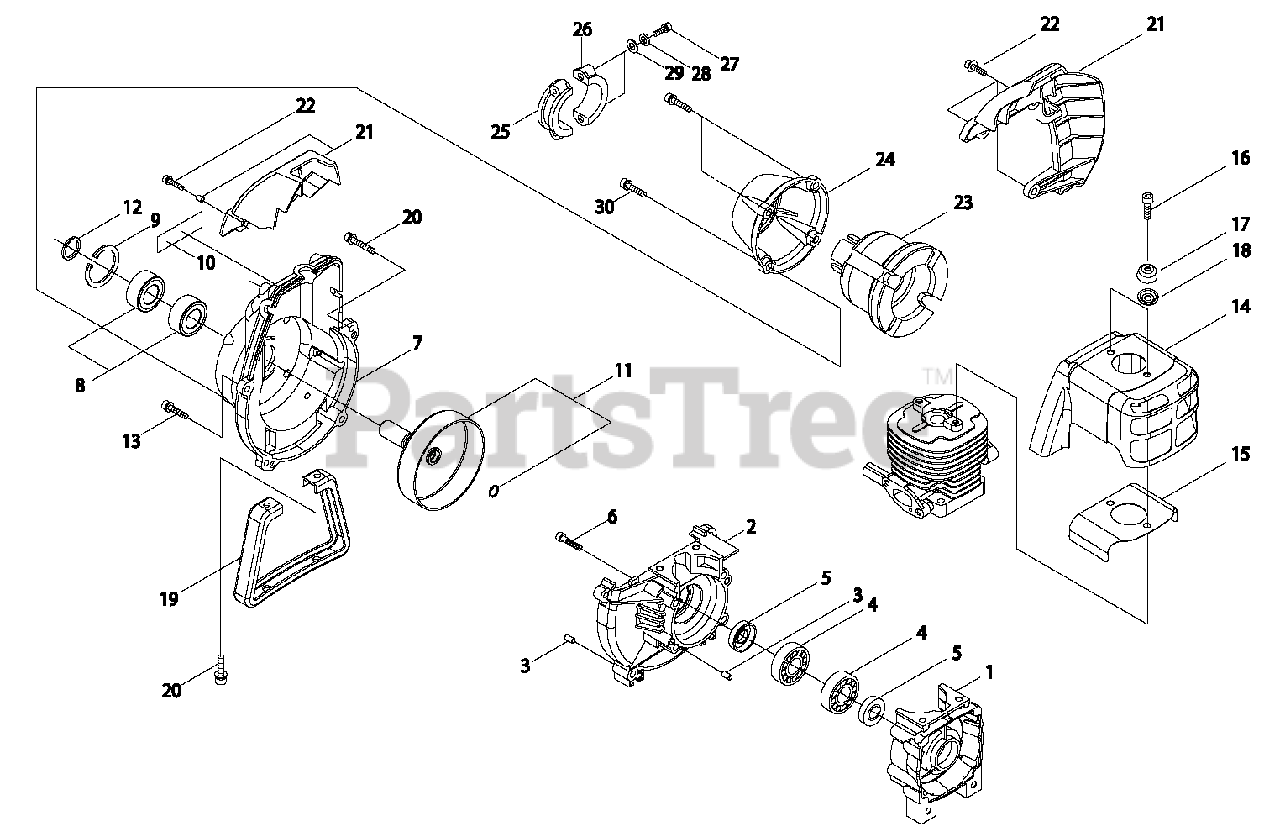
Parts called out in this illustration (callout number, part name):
1	CRANKCASE - REAR
2	CRANKCASE - FRONT
3	PIN - LOCATING
4	BEARING, BALL - 6202C3
5	SEAL, OIL - 15
6	SCREW - 5X30
7	CASE, FAN
8	BEARING, BALL - 6002
9	RING, RETAINING - 32
10	NAME PLATE
11	DRUM, CLUTCH
12	RING, RETAINING
13	SCREW - 5X20
14	COVER, ENGINE
15	SHIELD, CYLINDER
16	SCREW - 5X14
17	COVER
18	WASHER
19	GUARD, FUEL TANK
20	SCREW - 5X16
21	PROTECTOR ASSY
22	SCREW - 4X16
23	CUSHION
24	CONNECTOR, CAP
25	CLAMP - A
26	CLAMP - B
27	SCREW - 5X25
28	LOCKWASHER - 5
29	WASHER - 5
30	SCREW - 5X20
